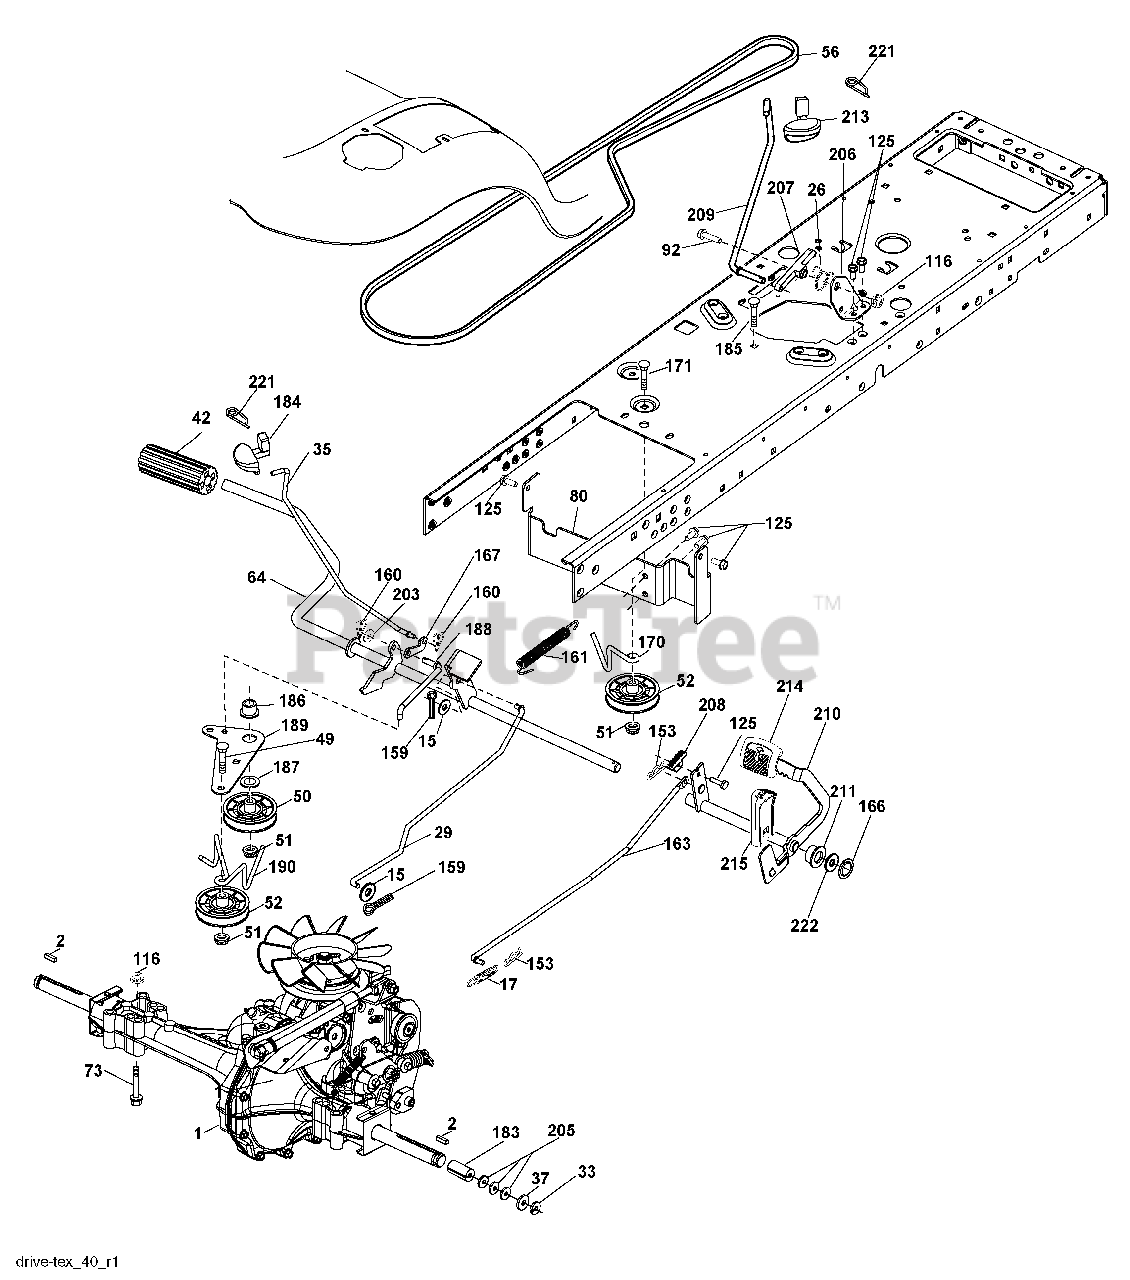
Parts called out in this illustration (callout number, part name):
2	Key
15	Washer 13/32 x 13/16 x 16 Ga.
17	Spring, Brake
26	Spring Return Cruise
29	Rod, Brake
33	Ring E #5133-75
35	Rod, Brake, Park
37	Washer 25/32 x 1-1/4 x 16 Ga.
42	Cover, Foot Pedal
49	Bolt
50	Pulley Idler Flat
51	Lock Nut 3/8-16
52	Idler V-Groove 910" Offset
56	V-Belt, Drive
64	Shaft Asm. Pedal Brake Control
73	Bolt Hex Flgnd 5/16-18 Gr 5
80	Bracket Strp. Trq.
92	Bolt Fin Hex 5/16-18 unc x 1.25
116	Nut Lock Hex Flange 5/16-18
125	Screw 5/16-18 x 3/4
153	Retainer Spring 1"
159	Pin Cotter 1/8 x 3/4
160	Retainer Clip
161	Spring, Return, Clutch
163	Rod Pedal Control
166	Nut Push .625
167	Latch Brake Parking
170	Keeper Belt Centerspan
171	Bolt
183	Spacer
184	Handle Parking Brake
185	Bolt
186	Spacer Retainer
187	Washer
188	Link Clutch Ground Drive
189	Bellcrank Ground Drive
190	Keeper Bellcrank Ground Drive
203	Washer 11/32 x 11/16 x 16 Ga.
205	Washer 25/32 x 1-5/8 x 16 Ga.
206	Bracket Mount Latch Cruise
207	Latch Control Cruise
208	Gear Sector Control Cruise
209	Rod Control Cruise
210	Rocker Asm. Pedal Control
211	Bearing Nylon Blk .629
213	Knob Control Cruise
214	Pedal Forward
215	Pedal Reverse
221	Retainer Spring Clip Handle
222	Washer 21/32 x 1-1/4 x 10 Ga.
